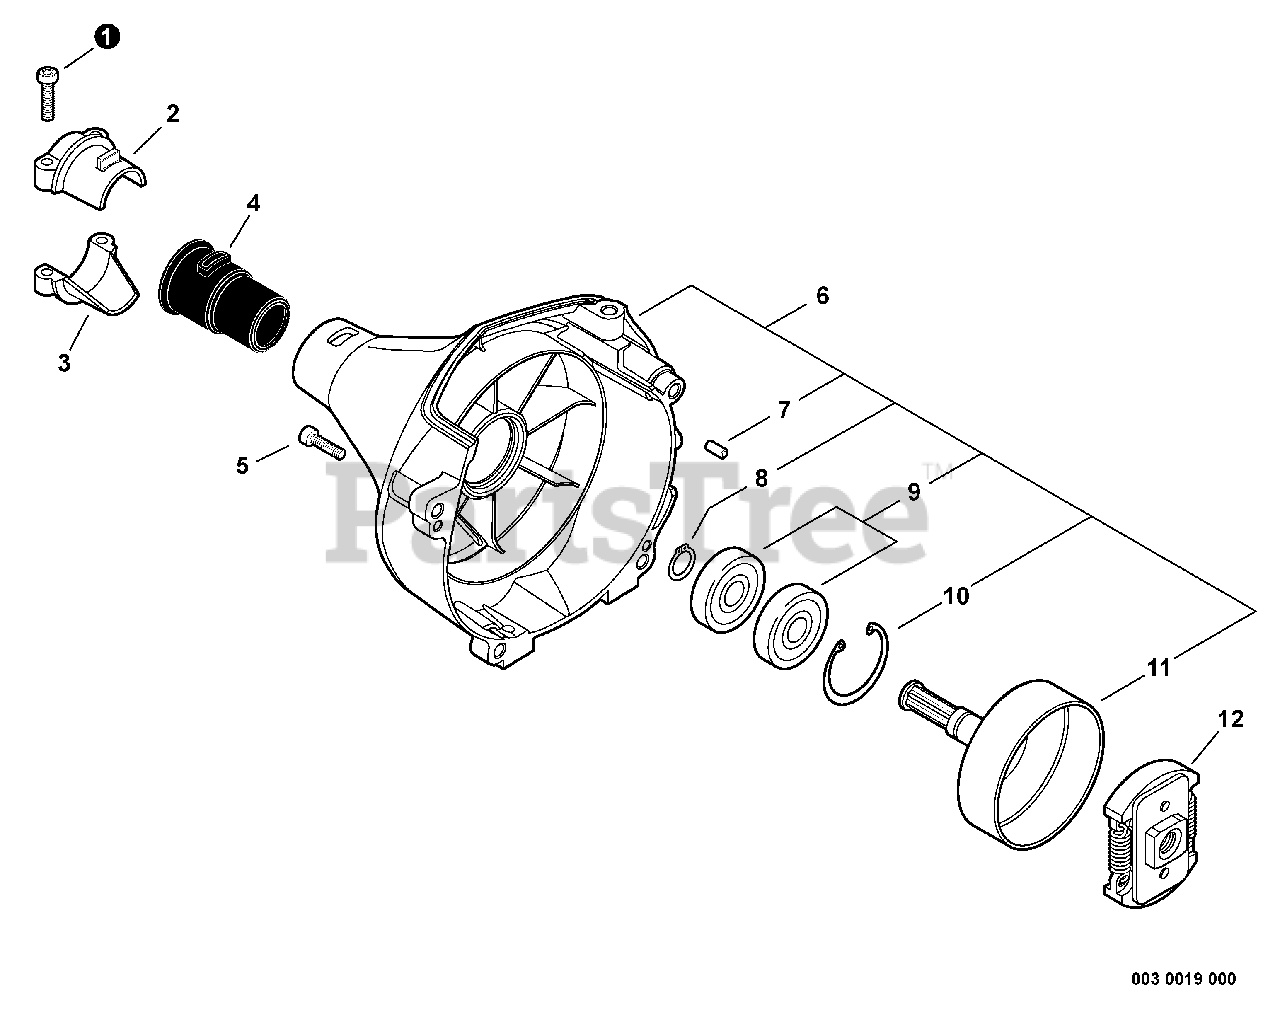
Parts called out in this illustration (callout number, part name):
1	BOLT, TORX 5×20
2	HOLDER, MAIN PIPE - UPPER
3	HOLDER, MAIN PIPE - LOWER
4	CUSHION Ø25
5	BOLT, TORX 4×16
6	COVER ASSY, FAN
7	PIN, LOCATING 4
8	RING, RETAINING - 12
9	BEARING, BALL 6001
10	RING, SNAP 28
11	DRUM, CLUTCH
12	CLUTCH ASSY
